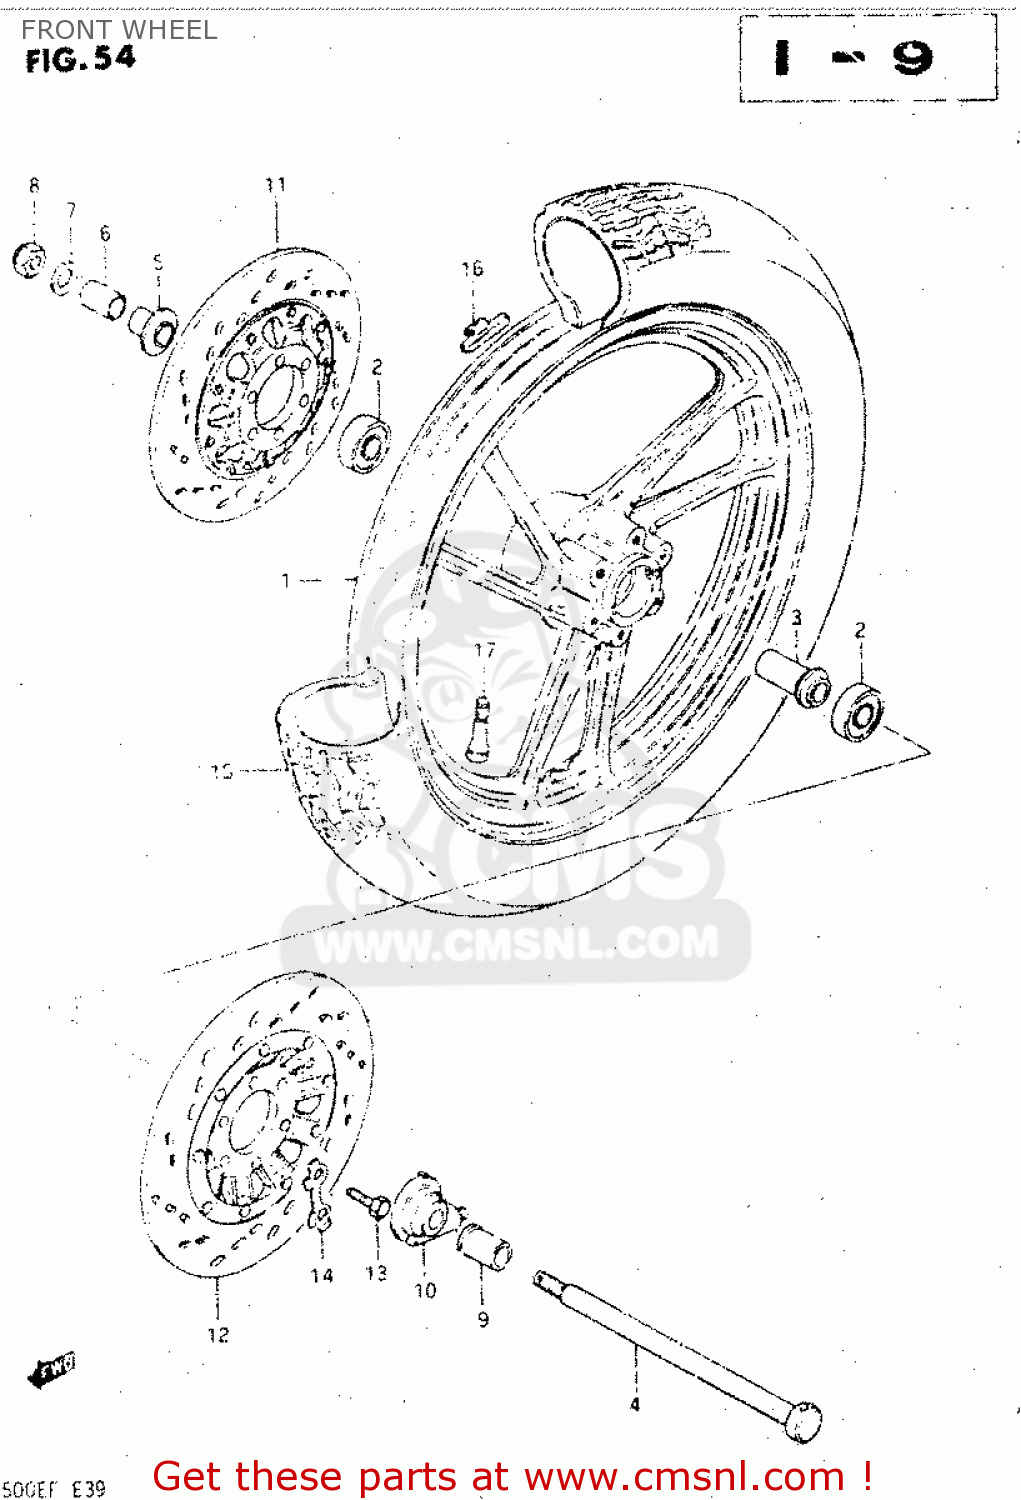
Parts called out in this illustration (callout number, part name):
1	WHEEL,FRONT
2	BEARING
3	SPACER,FR HUB BEARING
4	AXLE,FR
5	SPACER,FR AXLE,R
6	SPACER,FR AXLE,R
7	WASHER
8	NUT
9	SPACER,FR AXLE,L
10	BOX ASSY,SPEEDOMETER GEAR
11	DISC,BRAKE,RIGHT
12	DISC,BRAKE,LEFT
13	BOLT(8X30)
14	WASHER
15	TIRE,FRONT
16	BALANCER,WHEEL
17	VALVE,TIRE
